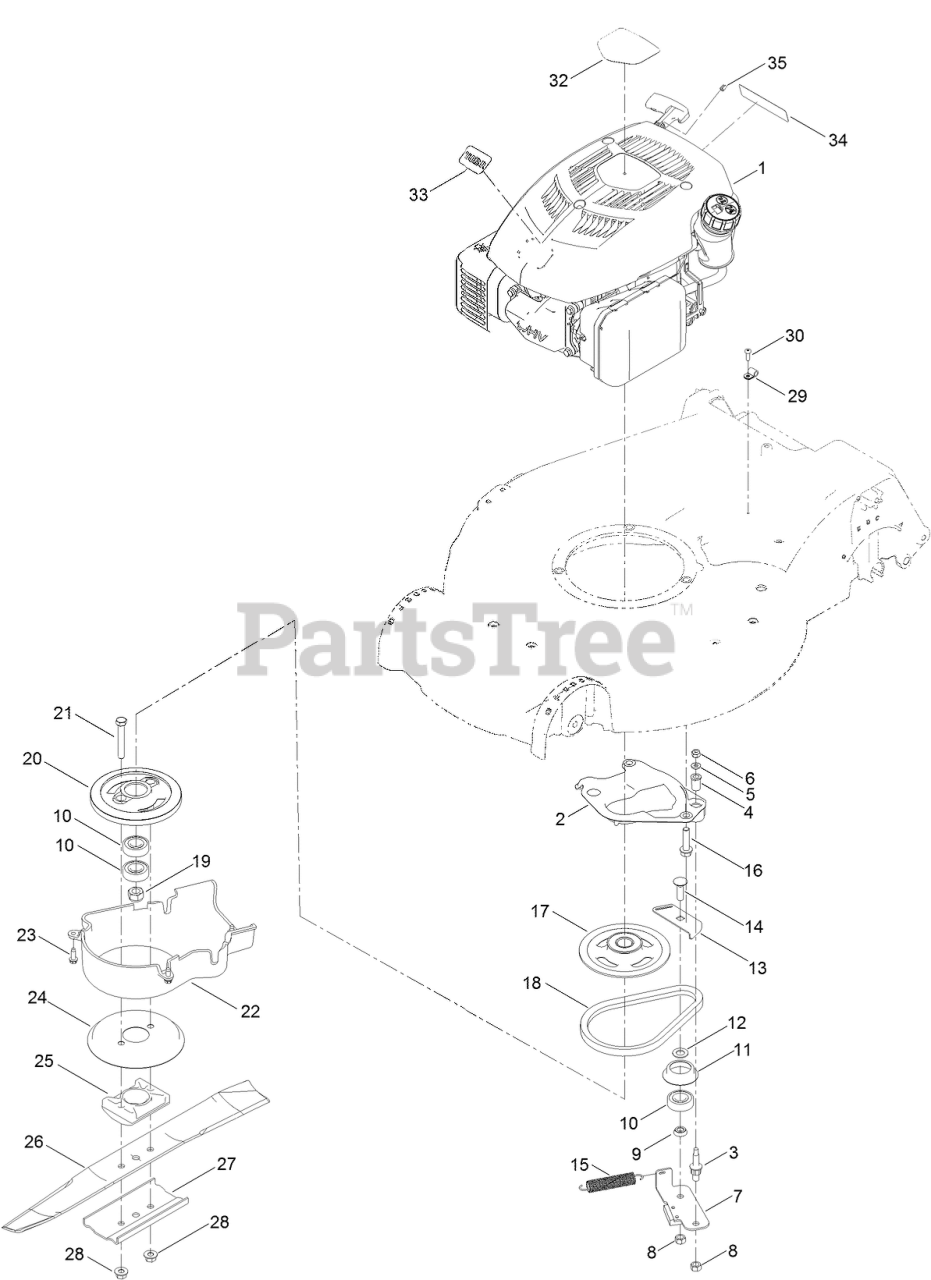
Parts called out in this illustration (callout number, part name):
1	ENGINE-1P65F-2
2	PLATE-ANCHOR
3	BOLT-SHOULDER
4	BUSHING
5	WASHER-FLAT
6	NUT-LOCK, NI
7	PLATE-BRAKE
8	LOCKNUT
9	SPACER-BEARING
10	BEARING-BALL
11	RETAINER-BELT
12	SPACER
13	PLATE-GUIDE
14	BOLT-CARR
15	SPRING-TENSION, BRAKE
16	SCREW-HWH
17	PULLEY
18	BELT
19	NUT-HEX
21	SCREW-HH
23	SCREW-HWHTF
25	SUPPORT-BLADE
26	BLADE-21IN, RECYCLING
27	SUPPORT-BLADE
28	NUT-FLANGE, LOCK
29	CLAMP
32	DECAL-SHROUD
34	DECAL-ARRESTOR, SPARK
35	STOP-ROPE
